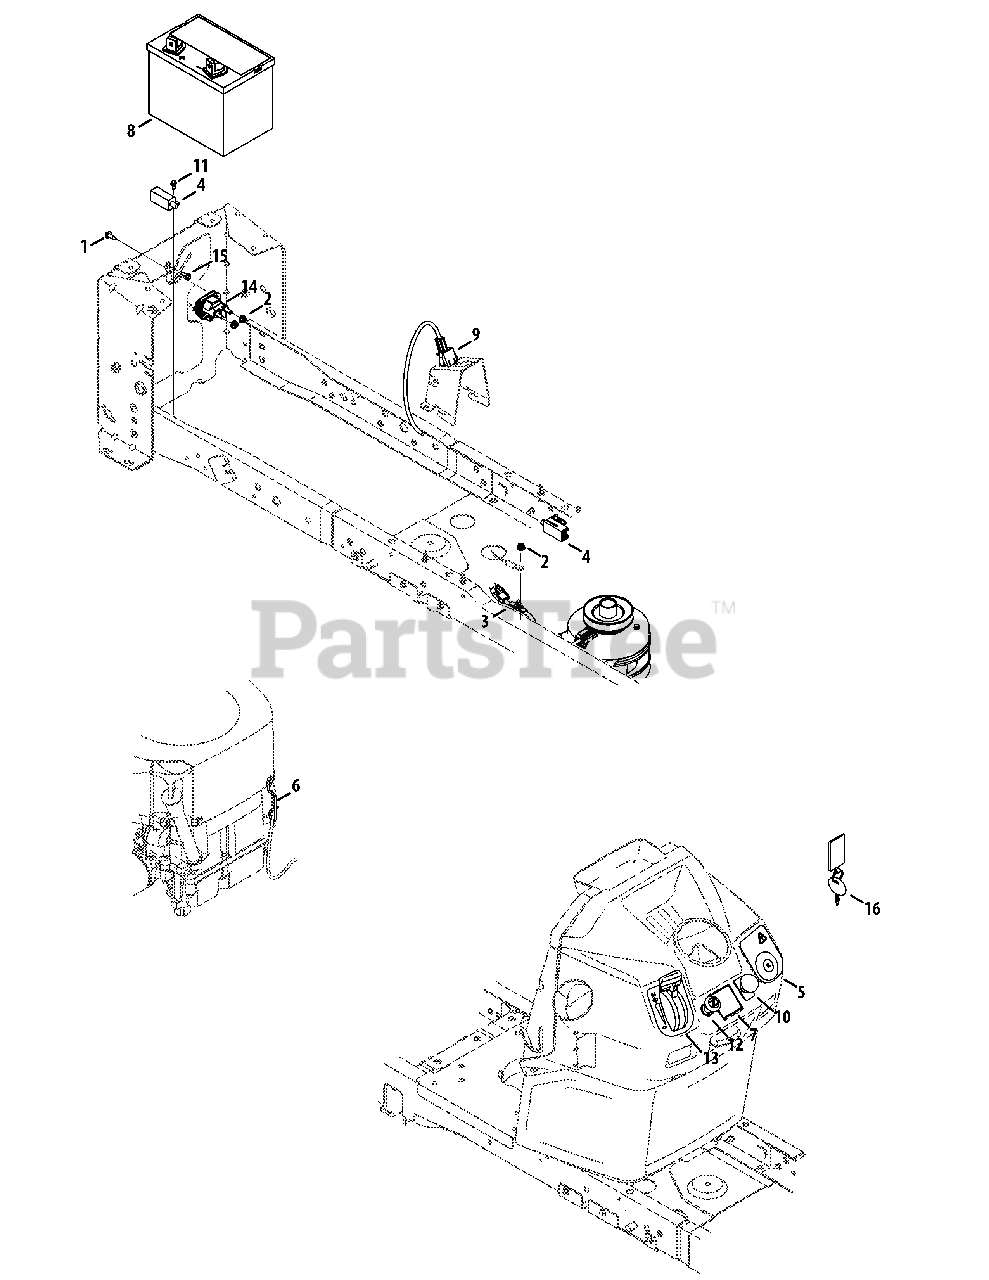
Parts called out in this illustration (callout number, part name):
1	Screw, M6-1 x .625
2	Nut, Jam Lock, 1/4-20, Nylon
3	Jumper Harness
4	Switch, Interlock
5	Key Switch
6	Cable Guide Rod
7	Hour Meter
8	Battery
9	Dash Harness
10	PTO Switch
11	Shoulder Screw, #10-32 x .500
12	Choke Plug
13	Throt/Choke Cable, 43.5"
14	Solenoid
15	Self-tapping Screw, 1/4-20 x .625
16	Key, Assembly
